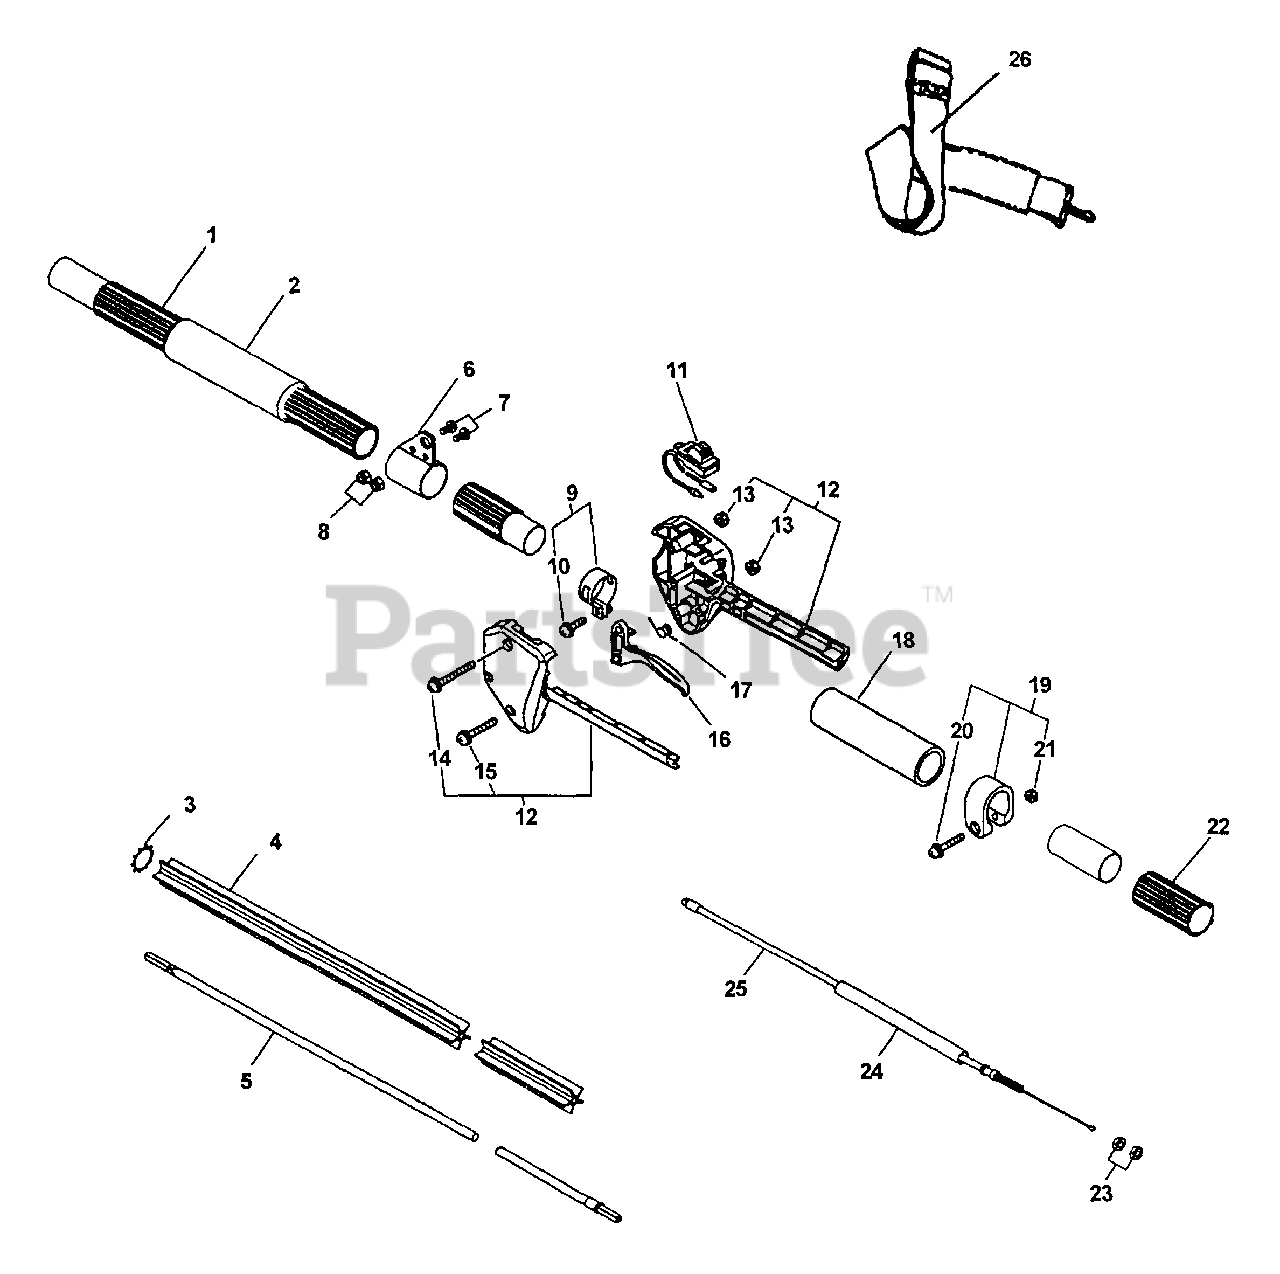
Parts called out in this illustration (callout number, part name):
1	MAIN PIPE ASSY
2	GRIP, FRONT - LEFT
3	LOCKWASHER - EXTERNAL
4	LINER - FLEXIBLE
5	DRIVESHAFT - FLEXIBLE
6	HANGER KIT
7	SCREW
8	LOCKNUT - 10-24
9	CLAMP KIT
10	SCREW - 5X14
11	IGNITION SWITCH ASSY
12	CONTROL HANDLE KIT
14	SCREW - 5X35
15	SCREW - 5X25
16	TRIGGER, THROTTLE
17	SPRING, TRIGGER
18	GRIP, HANDLE
19	CLAMP KIT
20	SCREW - 5X28
22	SLEEVE, HOUSING 2-5/8"
24	TUBE - VINYL
25	CABLE, THROTTLE
26	SHOULDER STRAP ASSY
